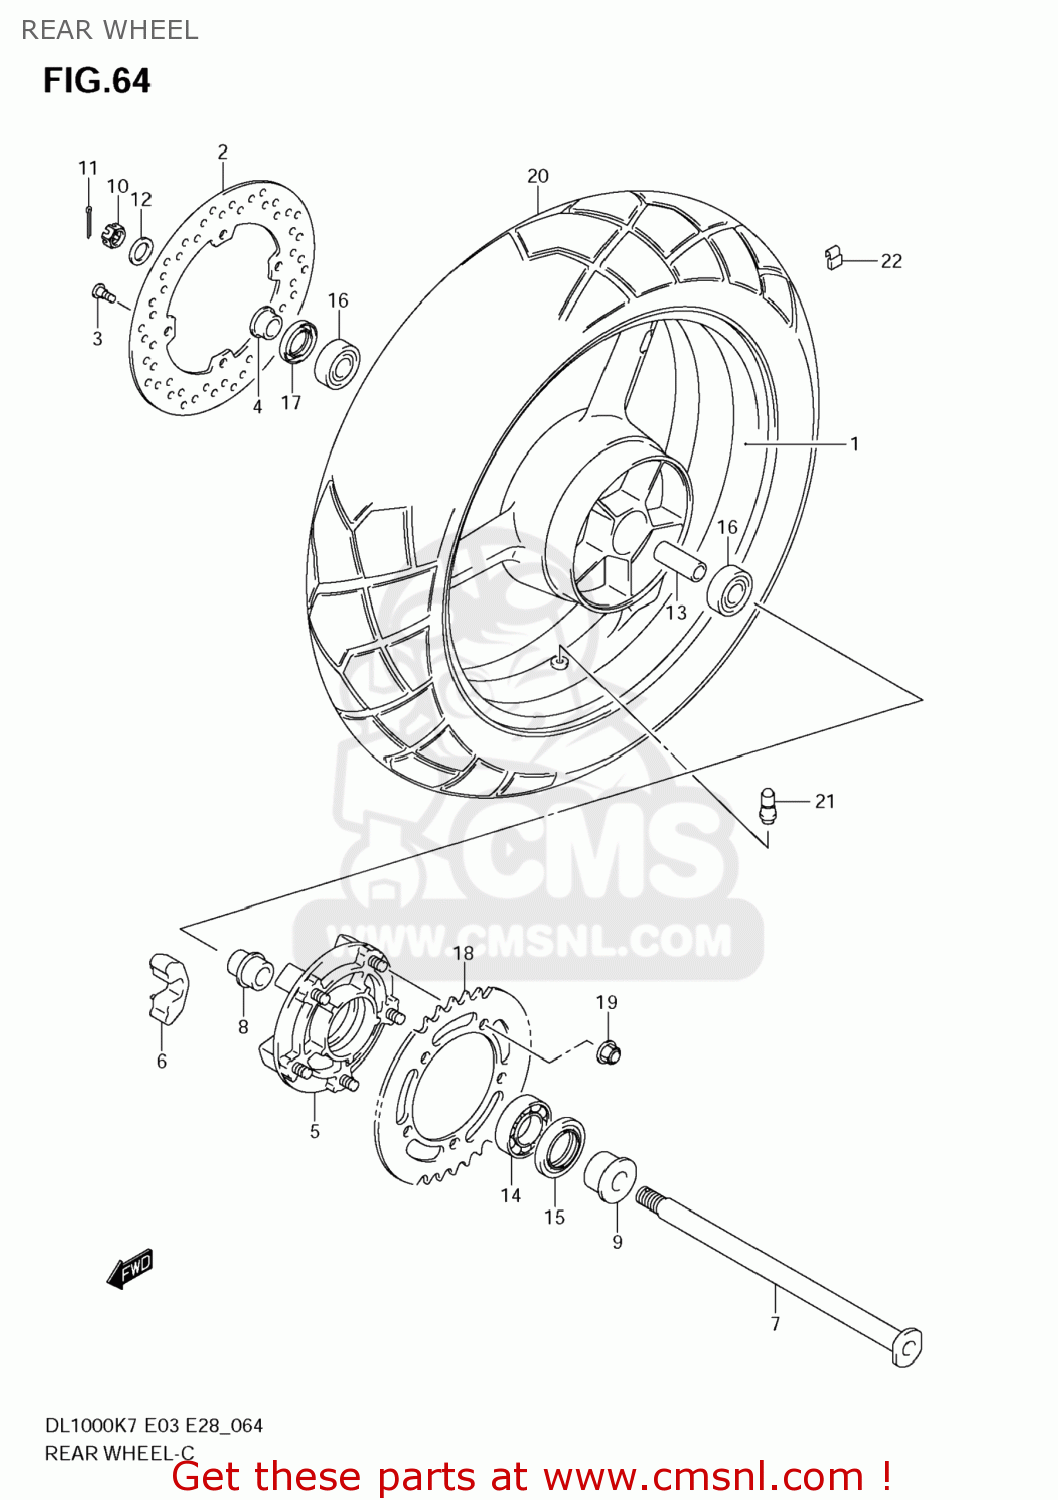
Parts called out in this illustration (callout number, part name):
1	WHEEL,RR(17M/CXMT4.00)
2	DISC,RR BRAKE
3	BOLT(8X21)
4	SPACER,RR AXLE,R
5	DRUM,RR SPROCKET
6	ABSORBER,RR HUB SHOCK
7	AXLE,RR
8	RETAINER,RR SPROCKET DRUM
9	SPACER,FR AXLE
10	NUT
11	PIN
12	WASHER(19X32X3.2)
13	SPACER(20.8X27.2X124)
14	BEARING
15	SEAL,OIL(39X65X7)
16	BEARING
17	SEAL,OIL(28X47X7)
18	SPROCKET,RR(NT:41-525)
19	NUT
20	TIRE,REAR,150/
21	VALVE ASSY,WHEEL RIM(TR412)
22	WEIGHT,WHEEL BALANCE 10G
